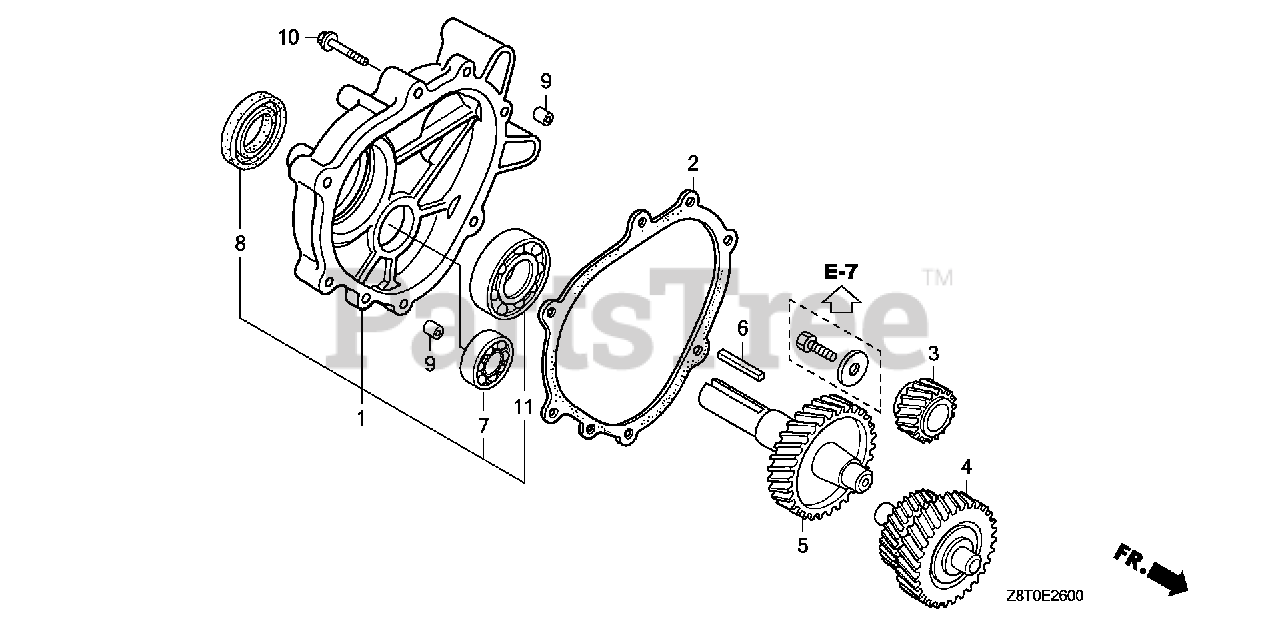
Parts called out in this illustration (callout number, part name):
1	COVER ASSY., GEAR CASE
2	GASKET, CHAIN CASE COVER
3	GEAR, PRIMARY DRIVE (22T)
4	COUNTERSHAFT (21T/27T)
5	SHAFT, P.T.O. (33T)
6	KEY (7X7X33) (OVER SIZE) (YELLOW)
7	BEARING, RADIAL BALL (6202) (NTN)
8	OIL SEAL (30X46X8) (NOK ASIA)
9	PIN, DOWEL (8X14)
10	BOLT, FLANGE (8X40)
11	BEARING, RADIAL BALL (6206)
